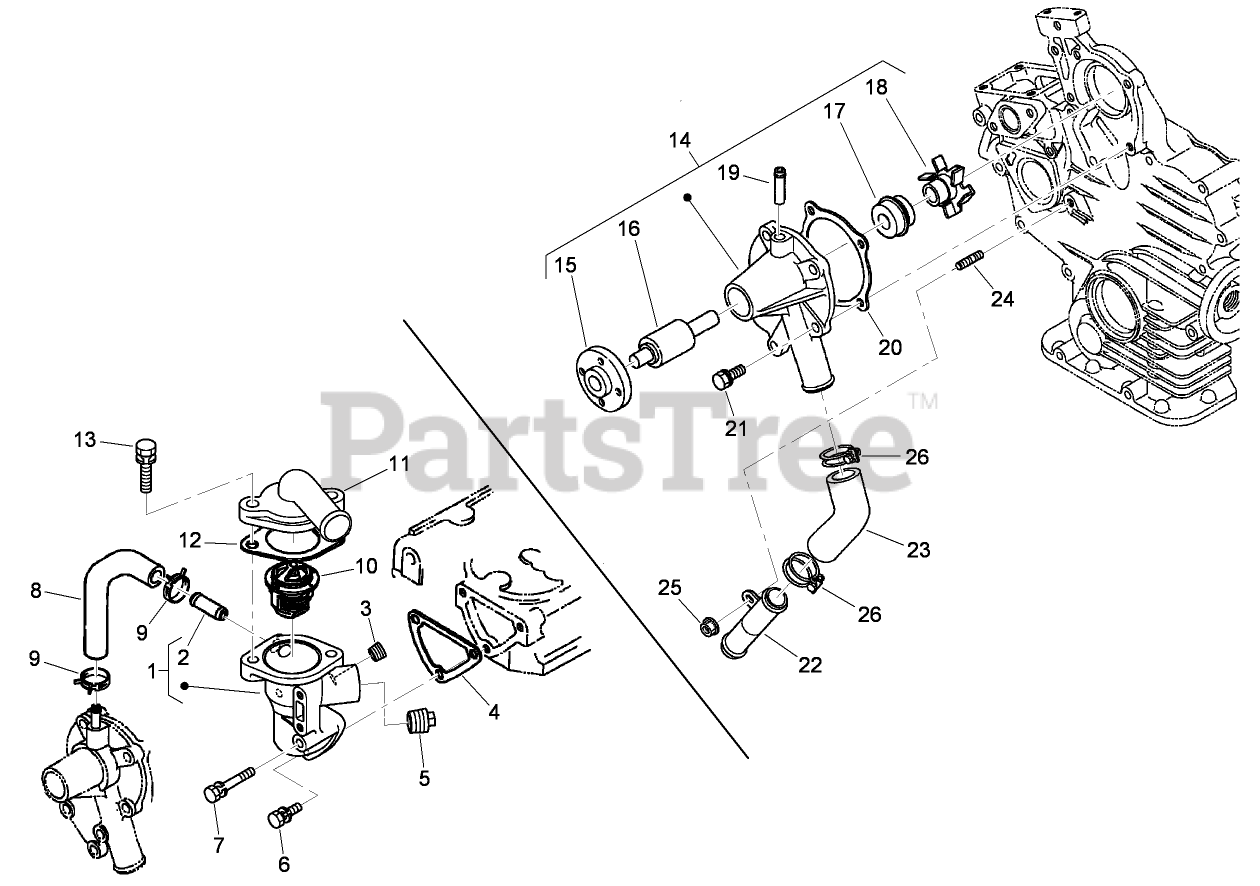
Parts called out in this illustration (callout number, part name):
1	WATER FLANGE ASM
2	PIPE-RETURN, WATER
4	GASKET-FLANGE, WATER
8	PIPE-RETURN, WATER
9	BAND-PIPE
10	THERMOSTAT ASM
11	COVER-THERMOSTAT
12	GASKET-THERMOSTAT
14	WATER PUMP ASM
15	FLANGE-PUMP, WATER
16	BEARING-BALL
17	WATER PUMP SEAL ASM
18	IMPELLER-PUMP, WATER
19	PIPE-RETURN, WATER
20	GASKET-PUMP, WATER
22	PIPE-WATER
23	PIPE-WATER
25	NUT-FLANGE
26	BAND-PIPE
